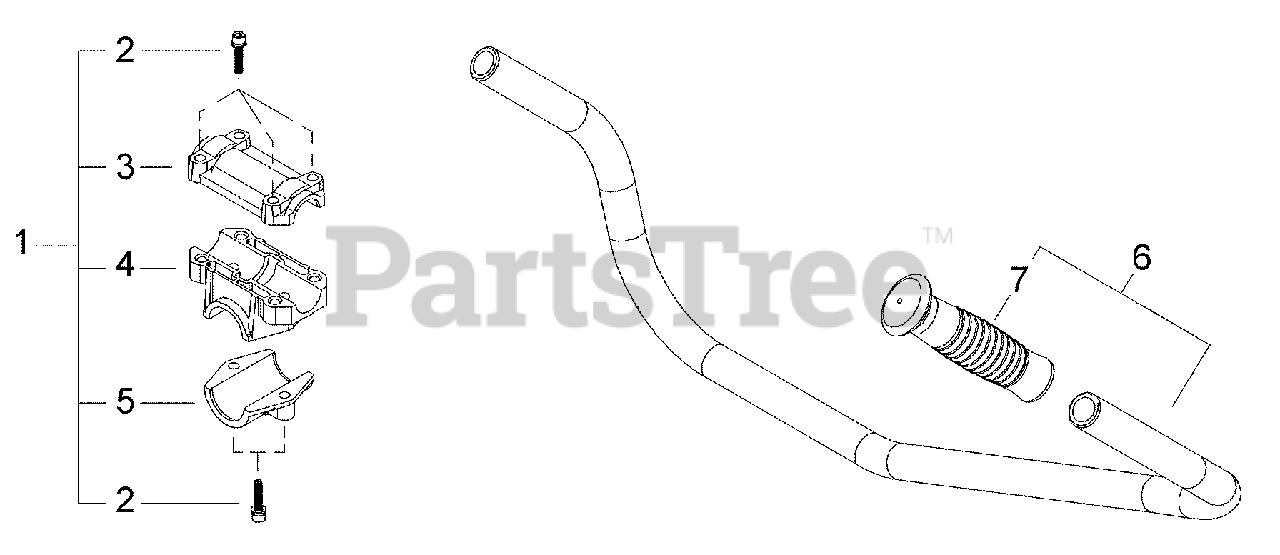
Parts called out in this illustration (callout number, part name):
1	HANDLE BRACKET KIT
2	SCREW - 5X25
3	BRACKET, HANDLE - UPPER
4	BRACKET, HANDLE - LOWER
5	BRACKET, MOUNTING
6	HANDLE ASSY
7	GRIP - LEFT
